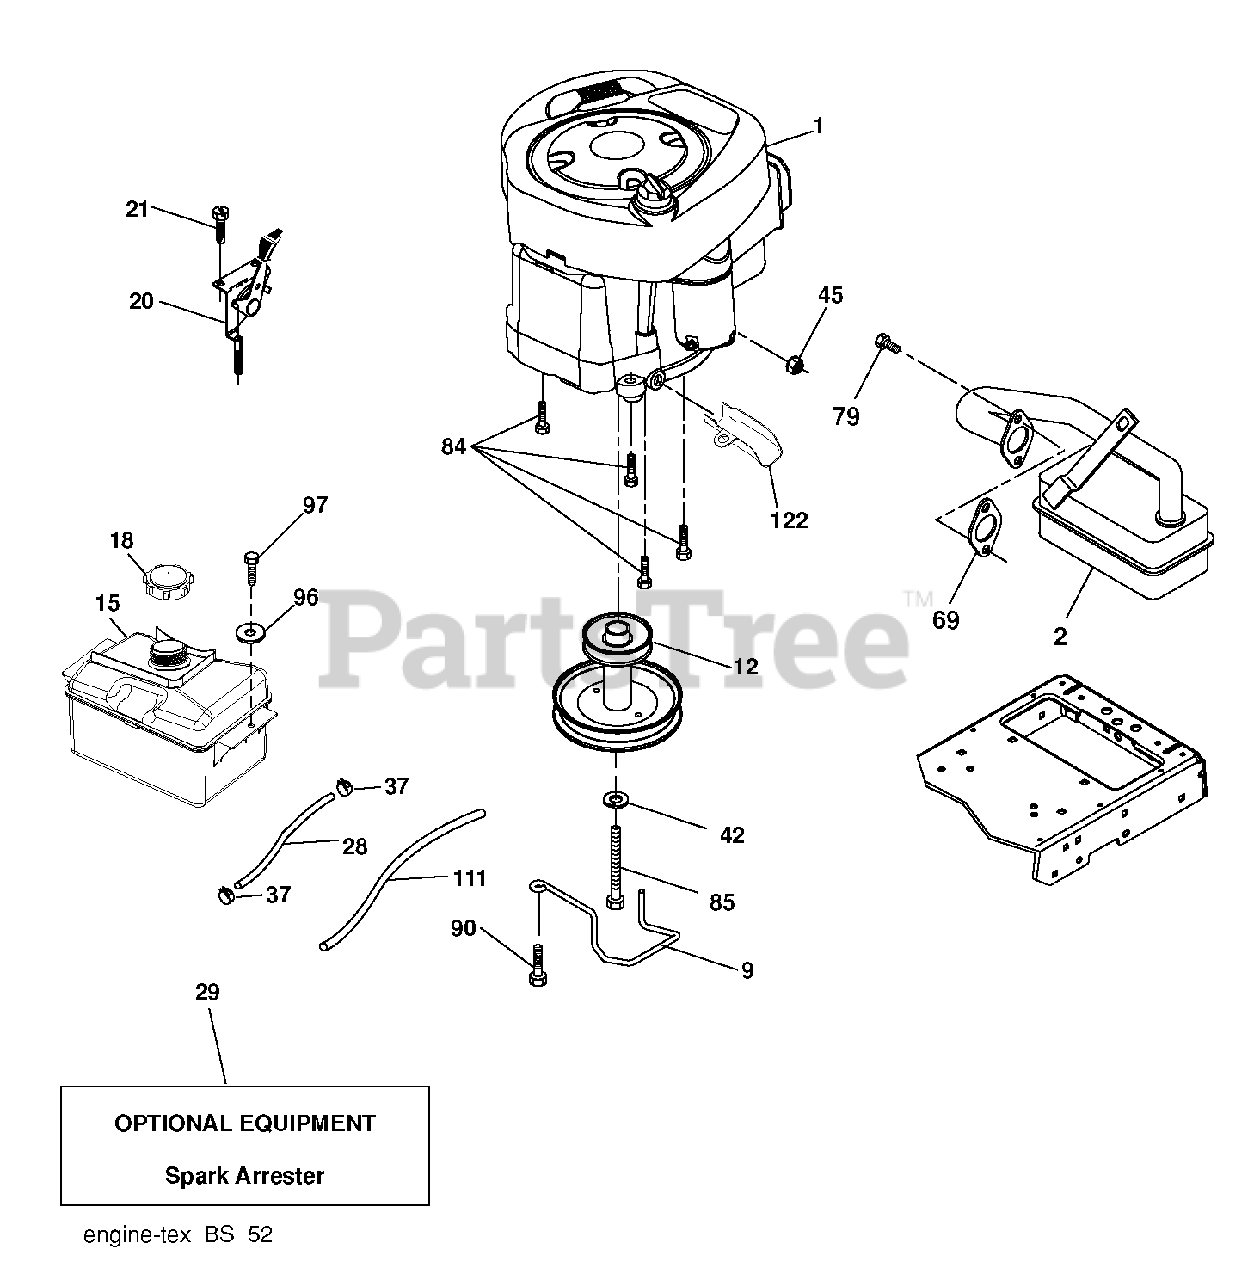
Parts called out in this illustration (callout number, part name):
2	MUFFLER.LT.BRIGGS.14HP.IC/OHV
9	KEEPER.BELT.ENGINE
12	Engine Pulley
15	TANK.ASM.1.5GAL.FRT.W/CAP.EPA
18	CAP.FUEL.2 WAY VENT
21	SCREW.#10 X 0.750.BOS (2 2)
28	LINE.FUEL.20"FRONT.EMI
29	KIT.SPARK ARRESTOR(392390 B&S)
37	HOSE CLAMP
42	LOCKWASHER
45	NUT
79	SCREW.SOCKET HD.5/16-1
84	SCREW.3/8-16
85	BOLT HEX 7/16-20X4-1/4"
90	SCREW 3/8-16X1
96	WASHER
97	SCREW HEXWSHR 1/4-20X3/4
111	RP PURGE LINE
122	EXTENSION DRAIN OIL
